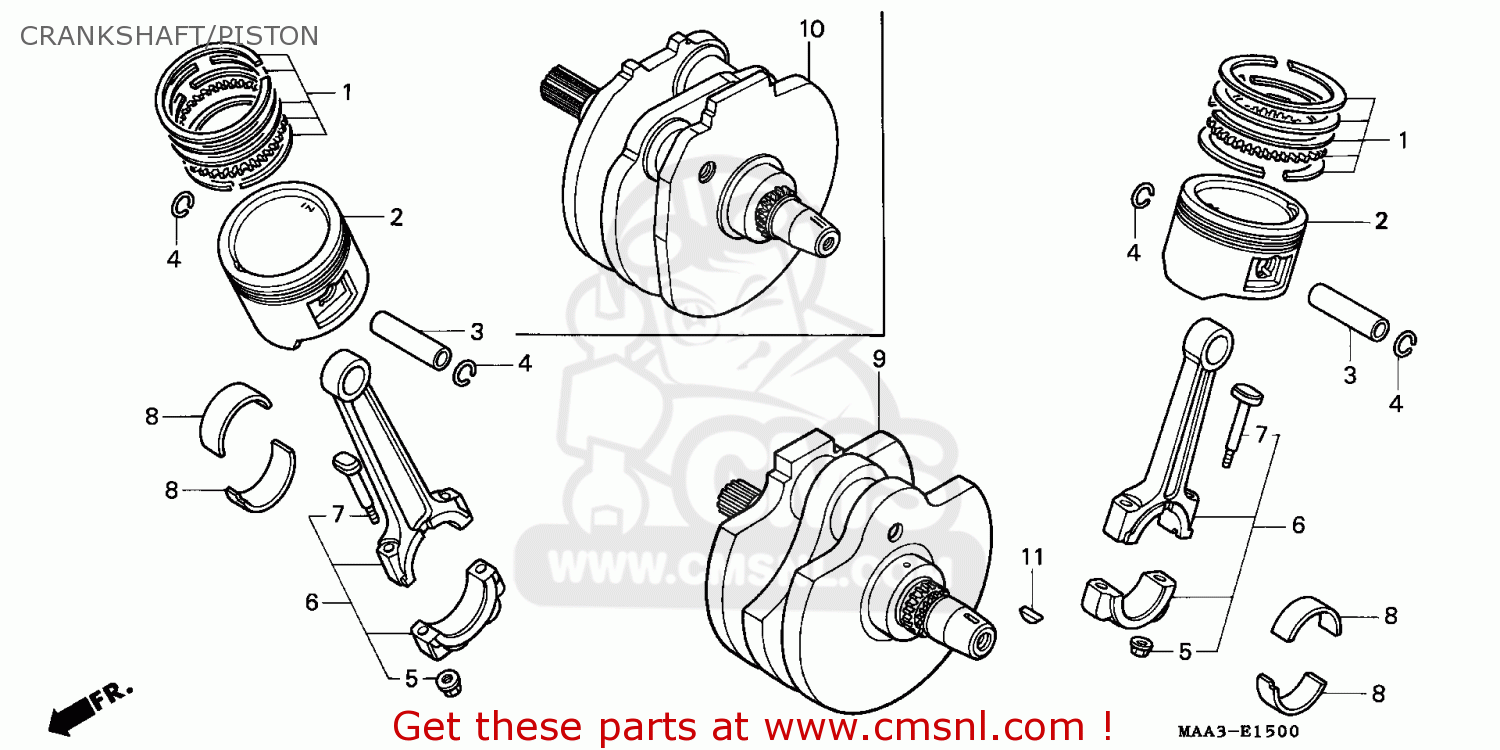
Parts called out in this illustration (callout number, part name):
1	RING SET.PISTON
2	PISTON
3	PIN,PISTON
4	CLIP,PISON,22MM
5	NUT
6	CONN ROD ASSY A
7	BOLT.CONN ROD
8	BRG A.CONN ROD
9	CRANKSHAFT COMP
11	KEY,SPL.WOODRUFF
